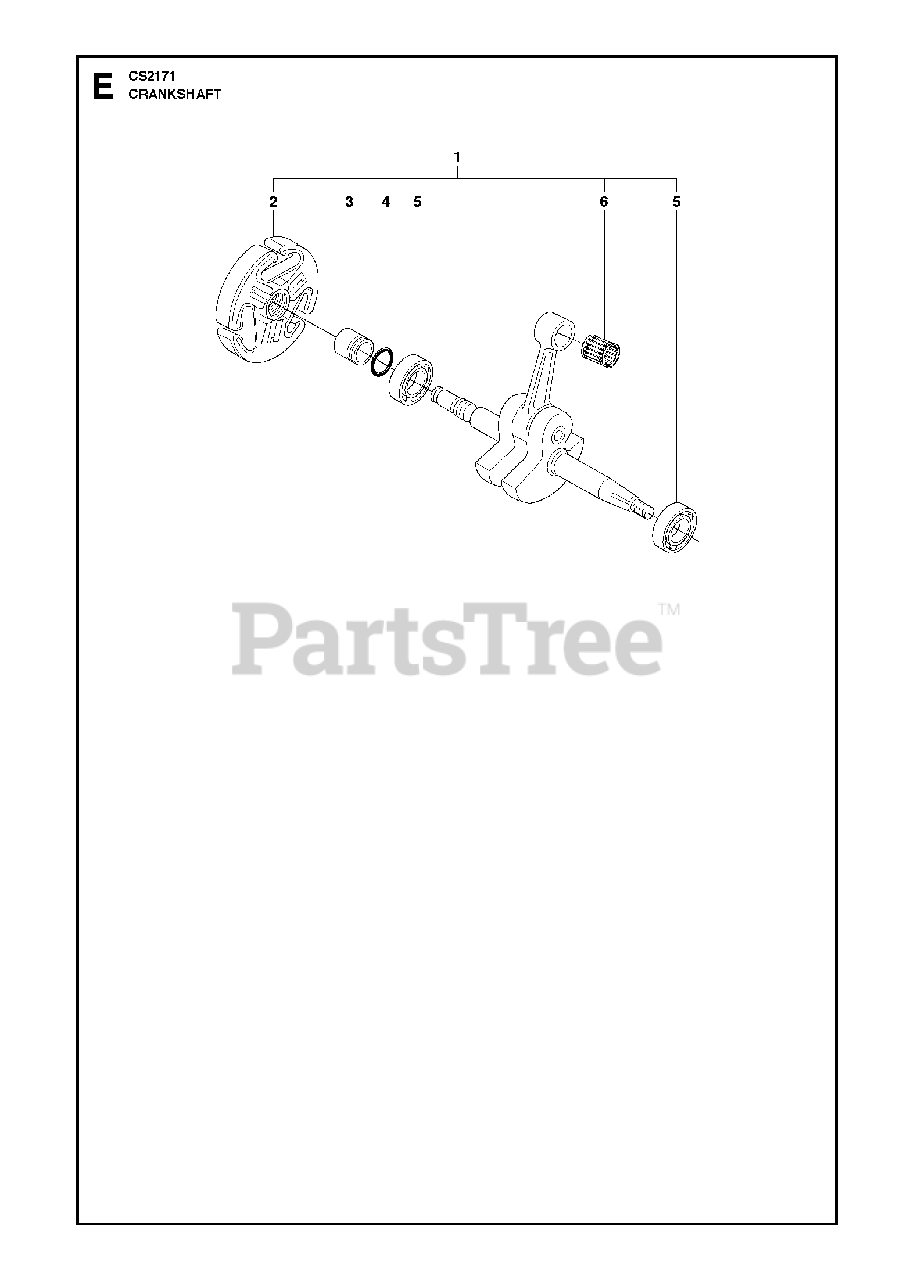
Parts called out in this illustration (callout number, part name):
1	CRANKSHAFT COMPLETE
2	CLUTCH
3	SLEEVE
4	O-RING
5	BALL BEARING-6202-C3 SKF
6	SUPPORT BUSHING
